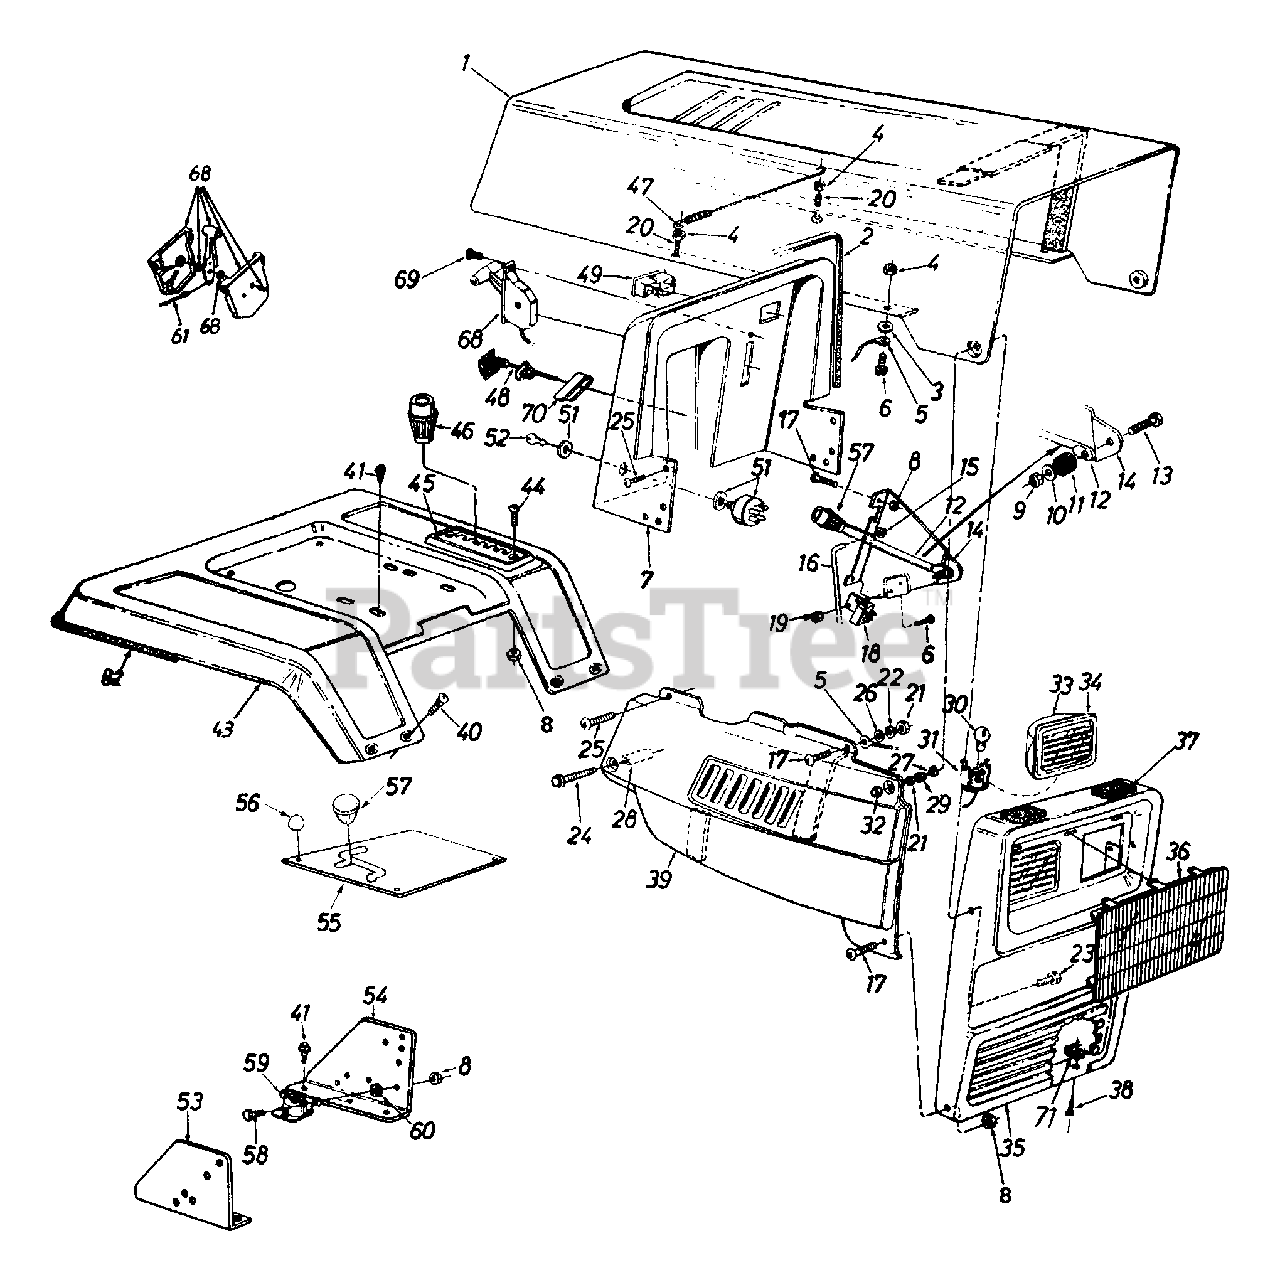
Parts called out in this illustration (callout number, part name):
3	Fl-Wash. .188" I.D. x .41" O.D.
4	Hex Sems Nut #10-24 Thd.
5	Hood Stop
6	Truss Mach. Scr. #10-24 x .5" Lg.
9	Hex L-Nut 1/4-20 Thd.
10	Fl-Wash. .281" I.D. x .73" O.D.
11	Rubber Washer
12	PTO Lever
13	Hex Bolt 1/4-20 x 1.25" Lg.
16	Deck Control Rod
17	Truss Mach. Scr. 1/4-20 x .5" Lg.
18	Safety Switch
19	Hex Sems Nut #10-24 Thd.
20	Hex Bolt 10-24 x 1.0" Lg.
21	Hex Nut 1/4-20 Thd.
22	L-Wash. 1/4" I.D.
23	Hex Bolt 1/4-20 x .88" Lg.
24	Hex Wash. TT-Tap Scr. 1/4-20 x 1.75" Lg.
25	Hex TT-Tap Scr. 1/4-20 x .75" Lg.
26	Fl-Wash. .25" I.D. x .62"
27	Spr. Wash. .39" I.D. x .62"
28	Spacer .26" I.D. x .375"
29	Shld. Spacer .375" Dia. x .125" Lg.
30	Lamp
31	Socket
32	Acorn Nut 1/4-20 Thd.
33	Headlight Housing
34	Headlight Lens
37	Foam Strip
38	Hex Bolt 5/16-18 x .75" Lg.
41	Hex Wash. AB-Tap Scr. 5/16 x .75" Lg.
45	6-Speed Selector Plate
46	Shift Knob
47	Hood Spring
48	Choke Control 46" Lg.
49	Ammeter
51	Ignition Switch
52	Ignition Key
57	Knob - Blade Clutch
58	Hex Bolt 1/4-20 x .5" Lg.
59	Solenoid
60	Ext. L-Wash. 1/4" I.D.
61	Throttle Wire 35" Lg.
68	Throttle Control Box Ass'y.
69	Truss Mach. AB-Tap Scr. #10 x .5" Lg.
70	Retainer Clip
71	U-Nut 5/16-18 Thd.
82	Trim Strip 81" Lg.
16725-0640	PANEL-SIDE RH - CO-OP GREEN (0640)
16725-0665	PANEL-SIDE RH - YARDMAN GREEN (0665)
16725-0691	PANEL-SIDE RH - BLACK JACK (0691)
17309B-0483	PANEL-SIDE-LH - CHARCOAL GRAY (0483)
17309B-0638	PANEL-SIDE-LH - MTD/TROY-BILT RED (0638)
17426A-0638	FENDER-RR - MTD/TROY-BILT RED (0638)
17426A-0648	FENDER-RR - TECH GRAY (0648)
